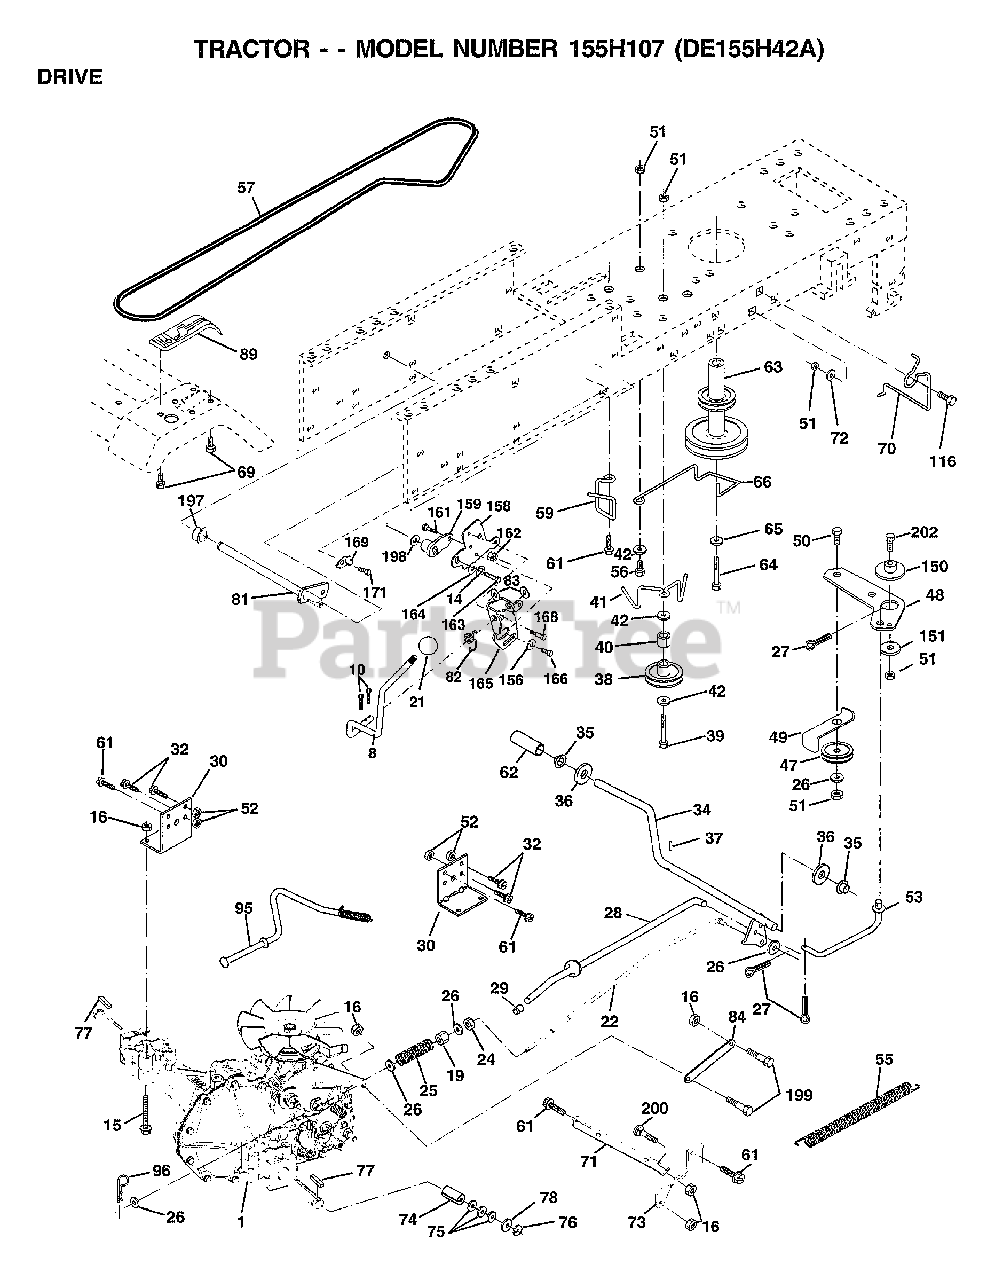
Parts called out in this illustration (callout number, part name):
8	ROD.SHIFT.FENDER.ADJ.LT.CRD
10	PIN COTTER 1/8
14	LOCKWASHER
15	BOLT.HX.FLG.5/16
16	NUT
19	NUT
21	KNOB T (1/2-HOLE)
22	ROD BRAKE HYDRO
24	NUT
25	SPRING ROD LT
26	WASHER
27	COTTER PIN
28	ROD.BRAKE.PARK.LT
29	PLUNGER CAP T
30	BRACKET MTG TRANSAXLE
32	BOLT
34	SHAFT ASM-PEDAL F
35	NYLON BEARING
36	WASHER LT
38	FLAT IDLER PULLEY
39	BOLT
40	SPACER T
41	"KEEPER,BELT.IDLER FLAT"
42	WASHER
48	BELLCRANK.CLUTCH
49	RETAIN BELT
53	"LINK, CLUTCH T"
55	"SPRING, RETURN LT"
57	"BELT.GD DRV 82"""
59	KEEPER BELT SPAN CTR
61	SCREW
62	PEDAL COVER T
63	PULLEY.ENGINE
64	BOLT
65	LOCKWASHER
66	KEEPER-BELT
69	SCREW HEXWSH H-L
70	KEEPER BELT ENG
71	STRAP TORQUE LH HYDRO
72	WASHER
73	STRAP TORQUE RH HYDRO
74	SPACER
75	WASHER
76	E-RING LT
77	SQUARE KEY
78	WASHER
81	SHAFT
82	"SPRING,TORSION"
83	WASHER
84	LINK TRANSAXLE
89	CONSOLE HYDRO
95	CONTROL ASSY
96	RETAINER M
116	BOLT RDHD 3/8-16
150	BUSHING.BELLCRANK.GRD.DR
151	WASHER
156	WASHER.SRRTD.5/16
158	BRKT.SHIFT.MOUNT
159	HUB.SHIFT
161	BOLT T
164	WASHER.5/8X.281X10GA
165	BRKT.PIVOT.LEVER
166	SCREW.5/16-18X5/8
168	BOLT.SHOULDER.5/16-18X.561
169	PLATE.FASTENING
171	SCREW LT
197	NYLINER SNAP-IN
198	WASHER NYLINER
199	BOLT SHOULDER
200	BOLT
202	BOLT.3/8-16X1.50
